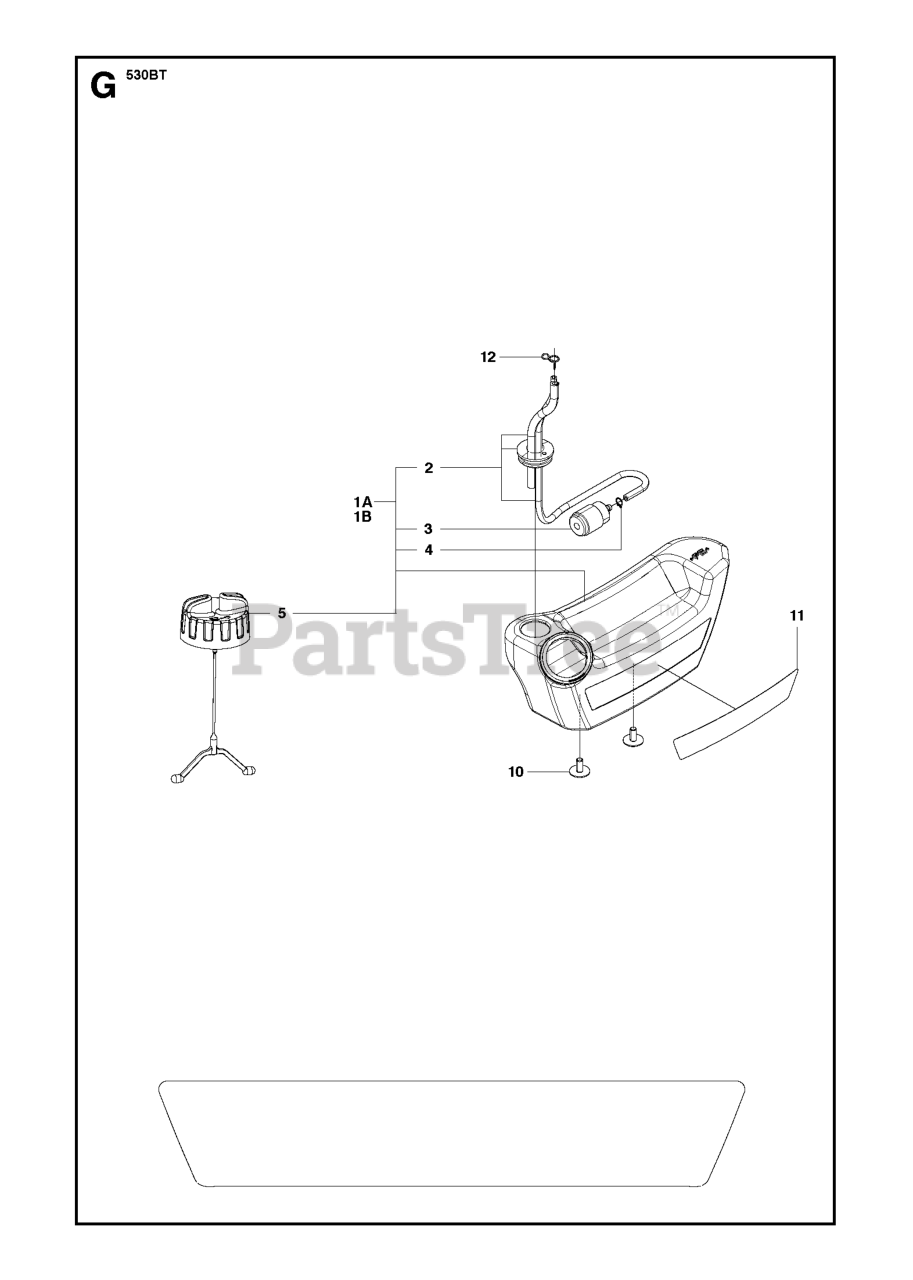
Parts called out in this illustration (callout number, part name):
1A	FUEL TANK ASSY EVAP
2	HOSE ASSY
3	RP FUEL FILTER
5	FUEL CAP ASSY
